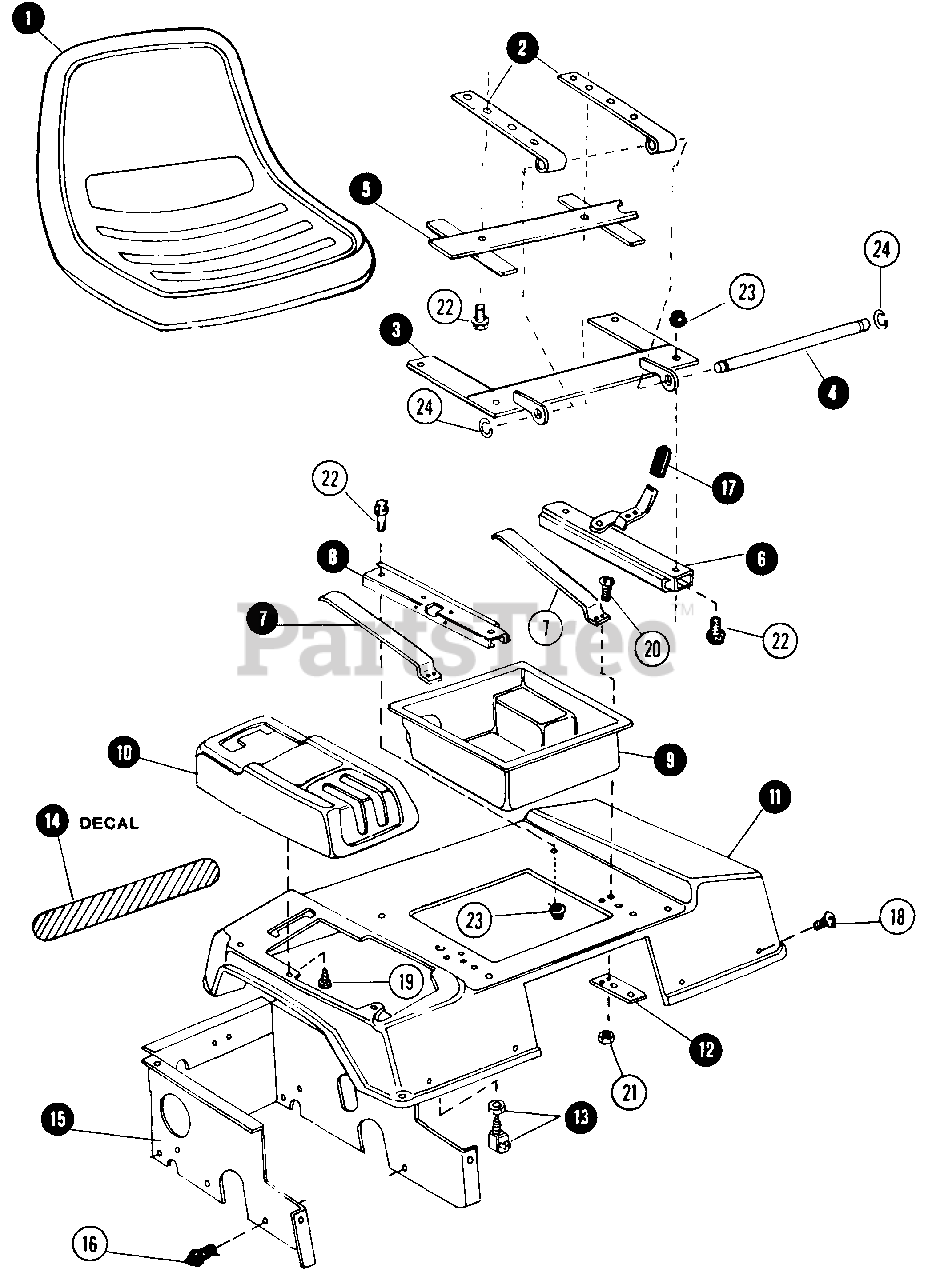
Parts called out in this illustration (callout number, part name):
1	SEAT, OPERATOR'S
2	STRAP, SEAT HINGE
3	HINGE, SEAT - ASSEMBLY
4	PIN, SEAT PIVOT
5	BAR, DEFLECTOR - ASSEMBLY
6	RAIL SEAT - ASSEMBLY
7	SPRING, SEAT
8	RAIL, SEAT - ASSEMBLY
9	COMPARTMENT
10	COVER, REAR FENDER
11	FENDER REAR
12	PLATE, SEAT RETAINER
13	SWITCH, SEAT INTERLOCK
14	DECAL, SNAPPER
15	RISER, REAR FENDER
16	BOLT, 3/8C x 7/8 HEX FLANGE LOCK
17	CAP, SEAT LATCH
18	SCREW, 5/16C x 5/8 ROUND HEAD
19	SCREW, 1/4C x 5/8 SELF-TAPPING
20	SCREW, 10-24 x 5/8 ROUND HEAD SLOTTED
21	NUT, #10-24 HEX LOCK - NYLON
22	BOLT, 5/16C x 5/8 HEX FLANGE LOCK
23	NUT, 5/16C HEX FLANGE
24	RING, RETAINING
